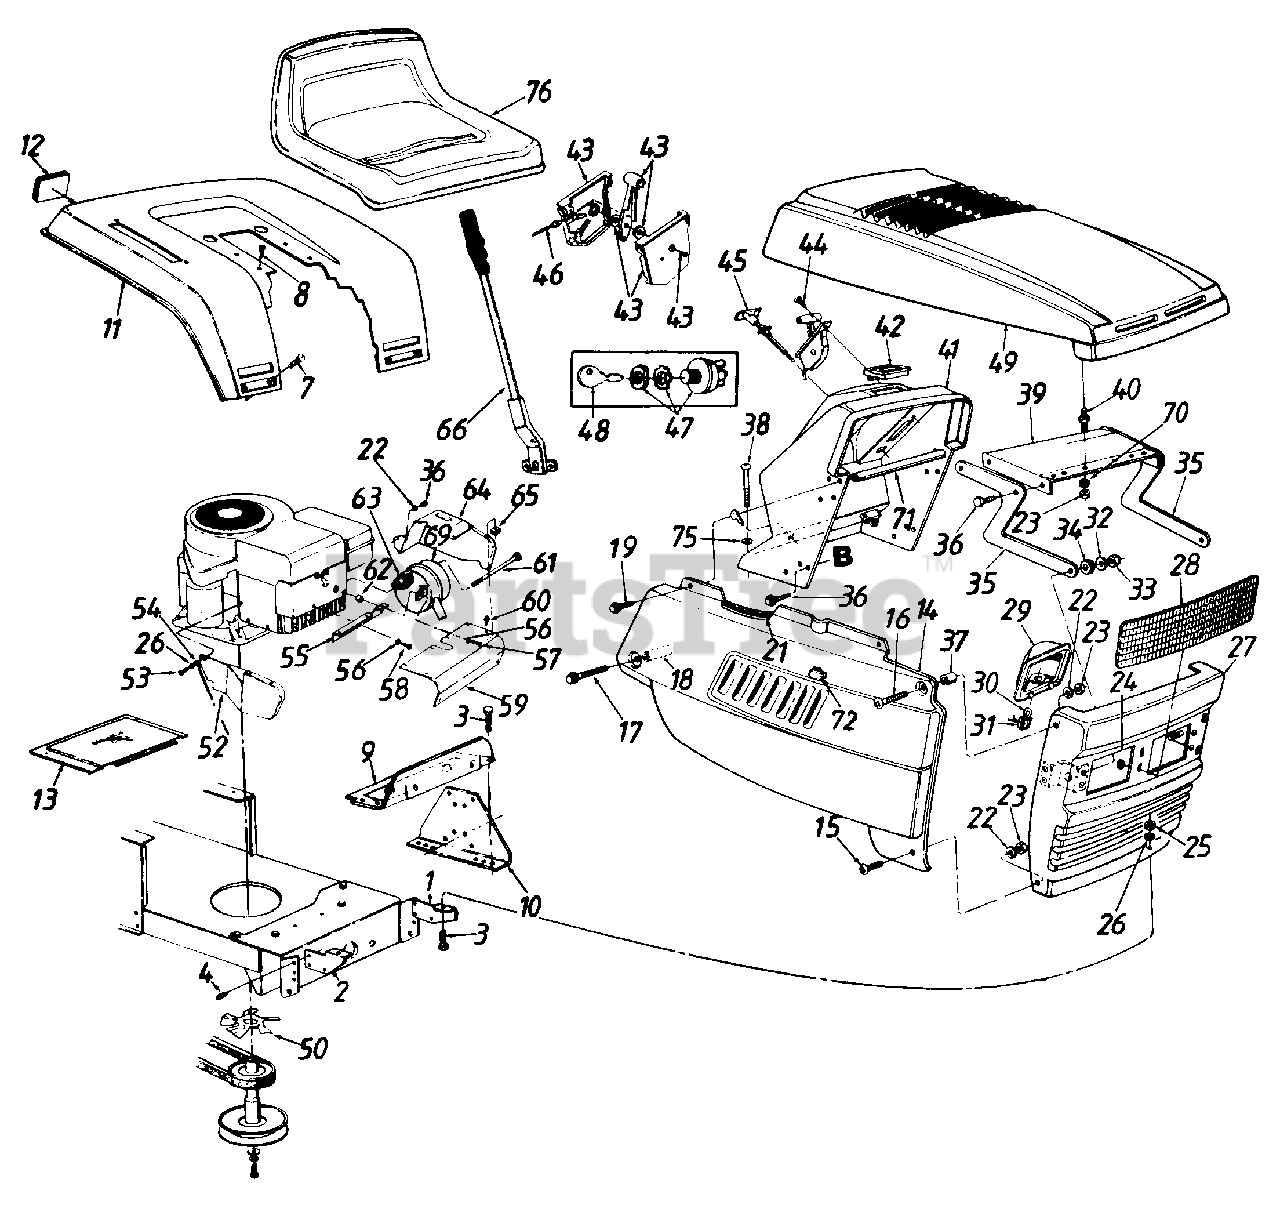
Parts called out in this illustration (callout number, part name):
1	Grille Mtg. Brkt. L.H.
4	Hex Wash. Hd. Tap Scr. 5/16-18 x .5" Lg.
7	Carriage Bolt 1/4-20 x .5" Lg.
8	Hex Wash. Hd. Tap Scr. 5/16 x .75" Lg.
9	Support Bracket
10	Dash Support Bracket
13	Transmission Cover
14	Side Panel R.H.
15	Truss Mach. Scr. 1/4-20 X .5" Lg.
16	Truss Mach. Scr. 1/4-20 X 1.0" Lg.
17	Hex Wash. TT-Tap Scr. 1/4-20 X 1.75" Lg.
18	Spacer .26" I.D. x 1.32"
19	Hex Rolling Tap Scr. 1/4-20 X .75" Lg.
21	Trim Strip 12" Lg.
22	L-Wash. 1/4" I.D.
23	Hex Nut 1/4-20 Thd.
24	Speed Nut 5/16" Thd.
25	Hex Nut 5/16-18 Thd.
26	L-Wash. 5/16" I.D.
29	Headlamp Housing
30	Headlamp
31	Twist Lock Lamp Socket
32	Bell-Wash. .345" I.D. x .88"
33	Hex L-Nut 5/16-18 Thd.
34	Rubber Washer
35	Hood Hinge
36	Hex Wash. Hd. B-Tap Scr. 1/4-20 x .5" Lg.
37	Spacer .265" I.D. x .376"
38	Mach. Scr. 1/4-20 x 1.5" Lg.
39	Hood Plate
40	Double Ended Stud 1/4-20 Thd.
42	Ammeter
43	Throttle Control Box Ass'y.
44	Mach. Scr. #10 x .44" Lg.
45	Choke Control 23" Lg.
46	Throttle Control Wire
47	Ignition Switch
48	Ignition Key
52	Muffler Heat Shield R.H.
53	Truss Mach. Scr. 5/16-18 x .75" Lg.
54	Ground Wire
55	Heat Shield Bracket
56	Spr. Wash. 1/4" I.D.
57	Hex Bolt 1/4-20 x .85" Lg.
58	Hex Bolt 1/4-20 x 3/8" Lg.
59	Muffler Heat Shield Front
60	Hex AB-Tap Scr. #10 x .5" Lg.
61	Shoulder Bolt
62	Spacer
63	Exhaust Gasket
64	Muffler Heat Shield L.H.
65	Speed Nut #10-24 Thd.
66	Lift Handle
69	Muffler
70	Bell-Wash. .265" I.D. x .75
71	Grille Support Tube
72	Mounting Clamp
75	Retaining Nut
76	Seat
